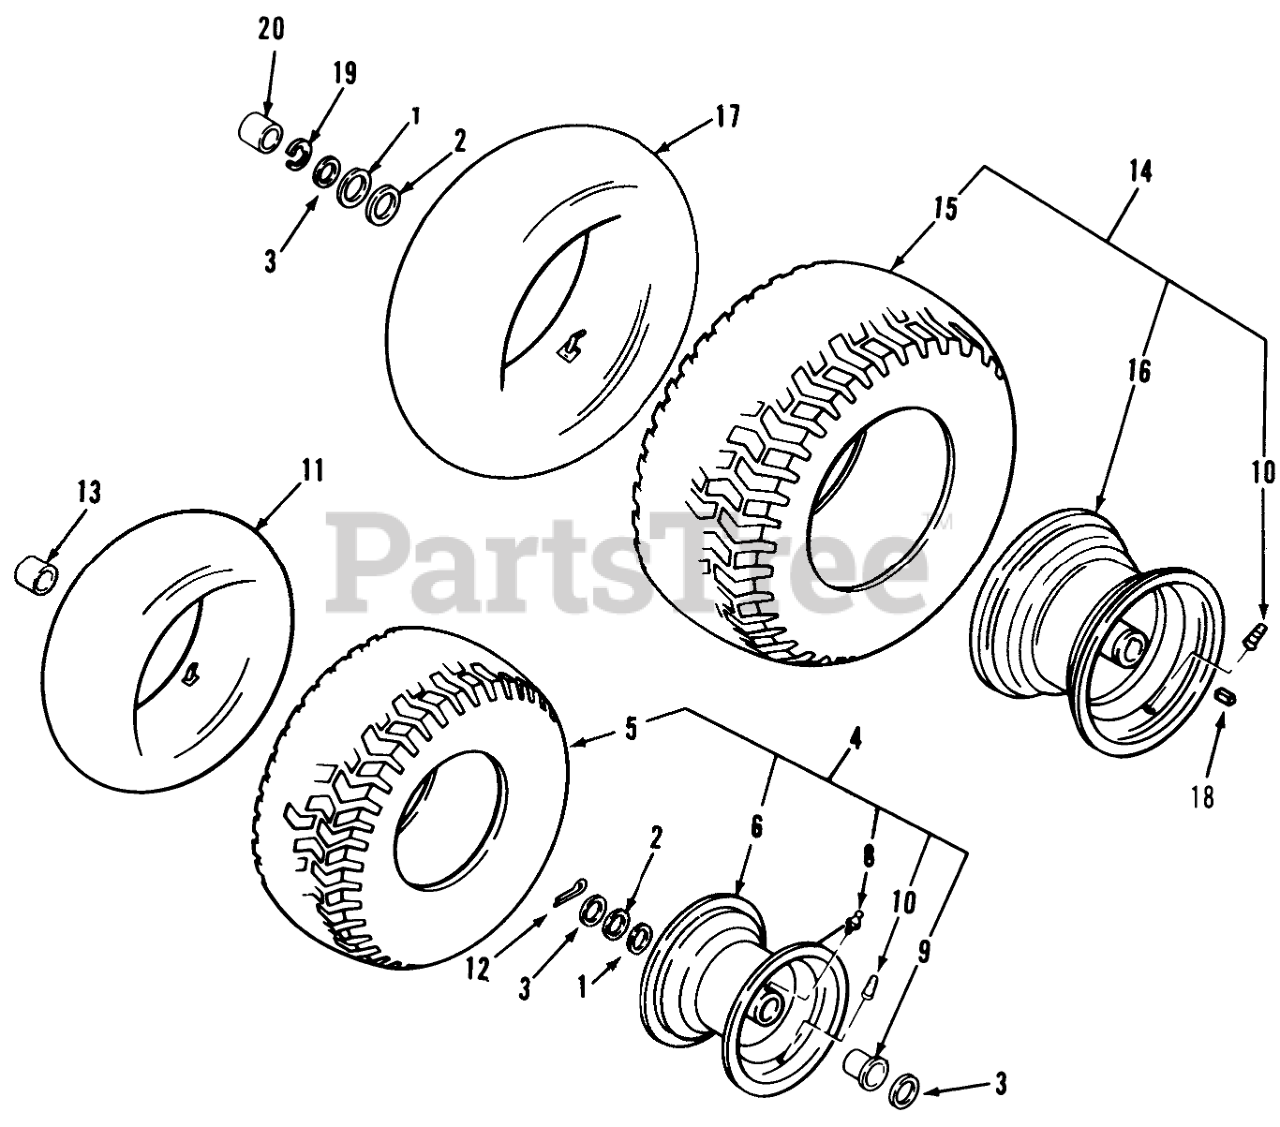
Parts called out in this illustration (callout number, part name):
1	WASHER-SHIM
2	WASHER
3	WASHER-FLAT
4	Front Wheel & Tire
5	Front Tire
6	Front Wheel (Includes Wheel w/items 8, 9 & 10)
8	ZERK-GREASE
9	Bearing
10	VALVE
12	PIN-COTTER
13	HUB CAP
14	Rear Wheel and Tire
15	TIRE-16 X 7.50 TURF
16	ASS'Y-WHEEL
17	Tube-Inner
18	SQ KEY
19	E Ring
20	HUB CAP-FLAT BLACK
